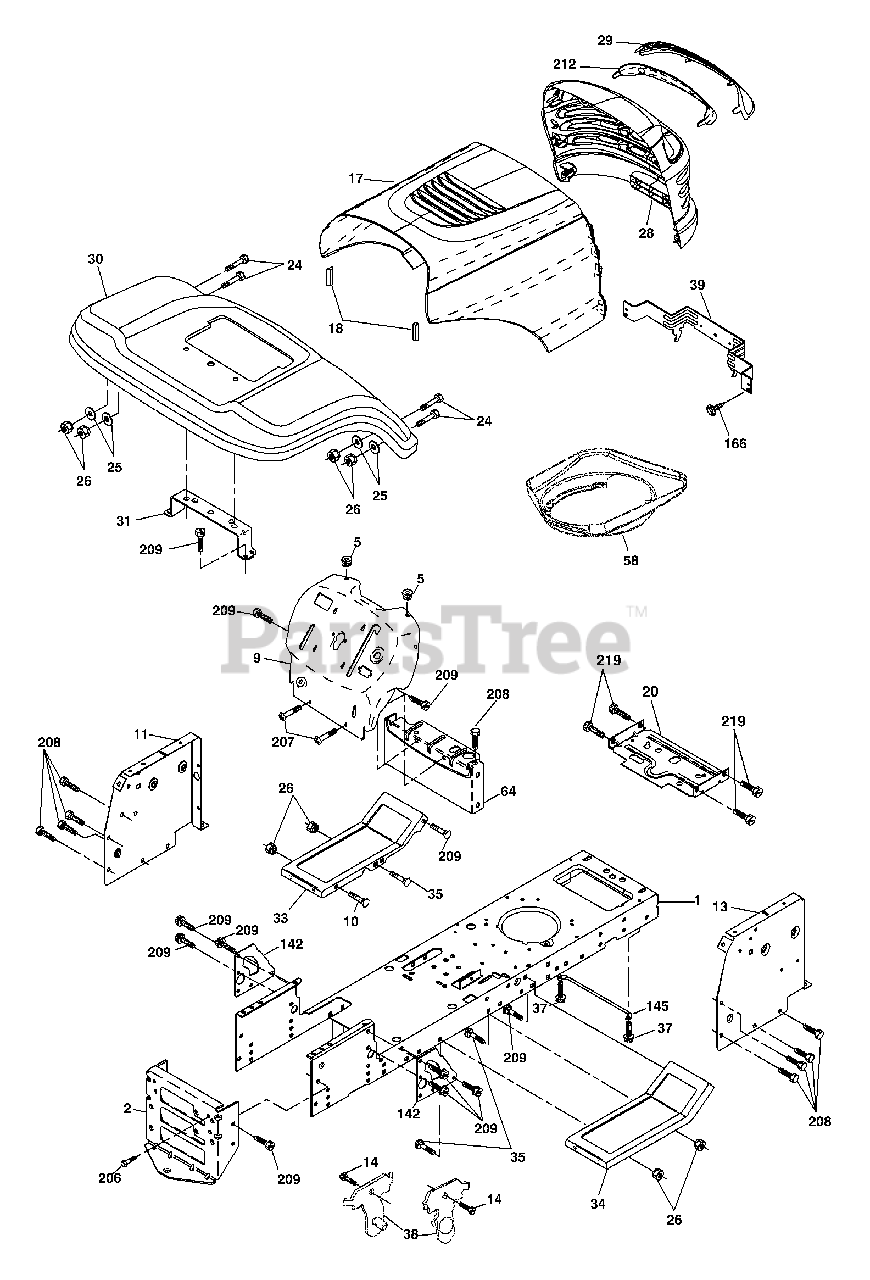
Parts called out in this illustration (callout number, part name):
1	Chassis
2	Drawbar
5	Bumper Hood/Dash
10	Bolt Carriage 3/8-16 x 1
11	Panel Dash Lh
12	Clip Tinnerman
14	Screw Thdrol 3/8-16 x 1-1/4
17	Hood
18	Bumper Hood
20	Tray
24	Bolt Fin Hex 3/8-16 x 1 Gr 5
25	Washer 13/32 X 13/16 X 12 Ga
26	Nut Lock Hex W/Ins 3/8-16 Unc
28	Grille Asm.
29	Lens
30	Fender Footrest LT Pnt
31	Bracket Support Fender
33	Footrest Pnt Lh
34	Footrest Pnt Rh
35	Bolt Rdhd Sht Sqnk 3/8-16 x 3/4
37	Screw Thdrol 6/16-18 x 1/2 TYT
38	Bracket Asm. Pivot Mower Rear
39	Bracket Pivot
64	Dash Lower STLT
142	Plate Reinforcement STLT
145	Rod Pivot Chassis/Hood
166	Screw
206	Bolt Shoulder 5/16-18
207	Screw Thdrol 5/16-18 x 1/2
208	Screw Thdrol 3/8-16 x 1/2
209	Screw Hex Wsh Thdr. 3/8-16 x 3/4
212	Insert Lens Reflect
219	Screw
